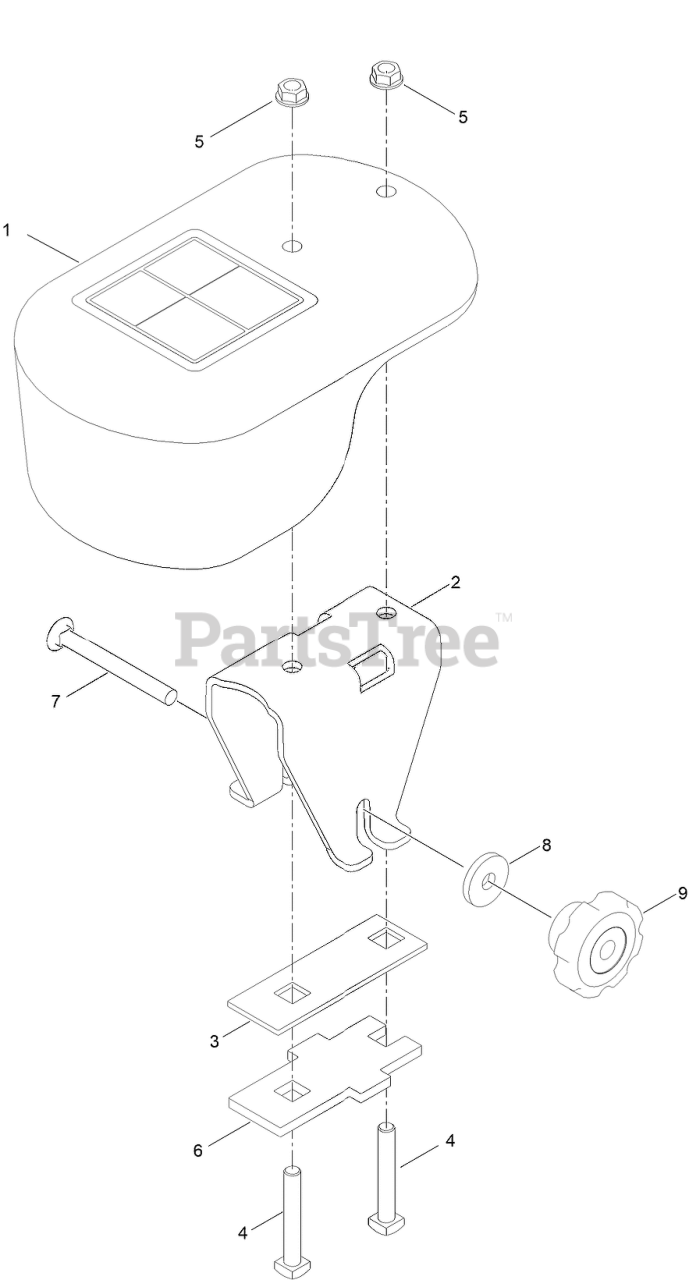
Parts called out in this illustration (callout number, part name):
1	WEIGHT WITH DECAL ASM
2	CHANNEL-MOUNT, WEIGHT
3	PLATE-BRACKET, WEIGHT
4	BOLT-SQH
5	NUT-HHF, WHIZ
6	PLATE-BRACKET, WEIGHT
7	SCREW-CARR
8	WASHER-BACKUP
